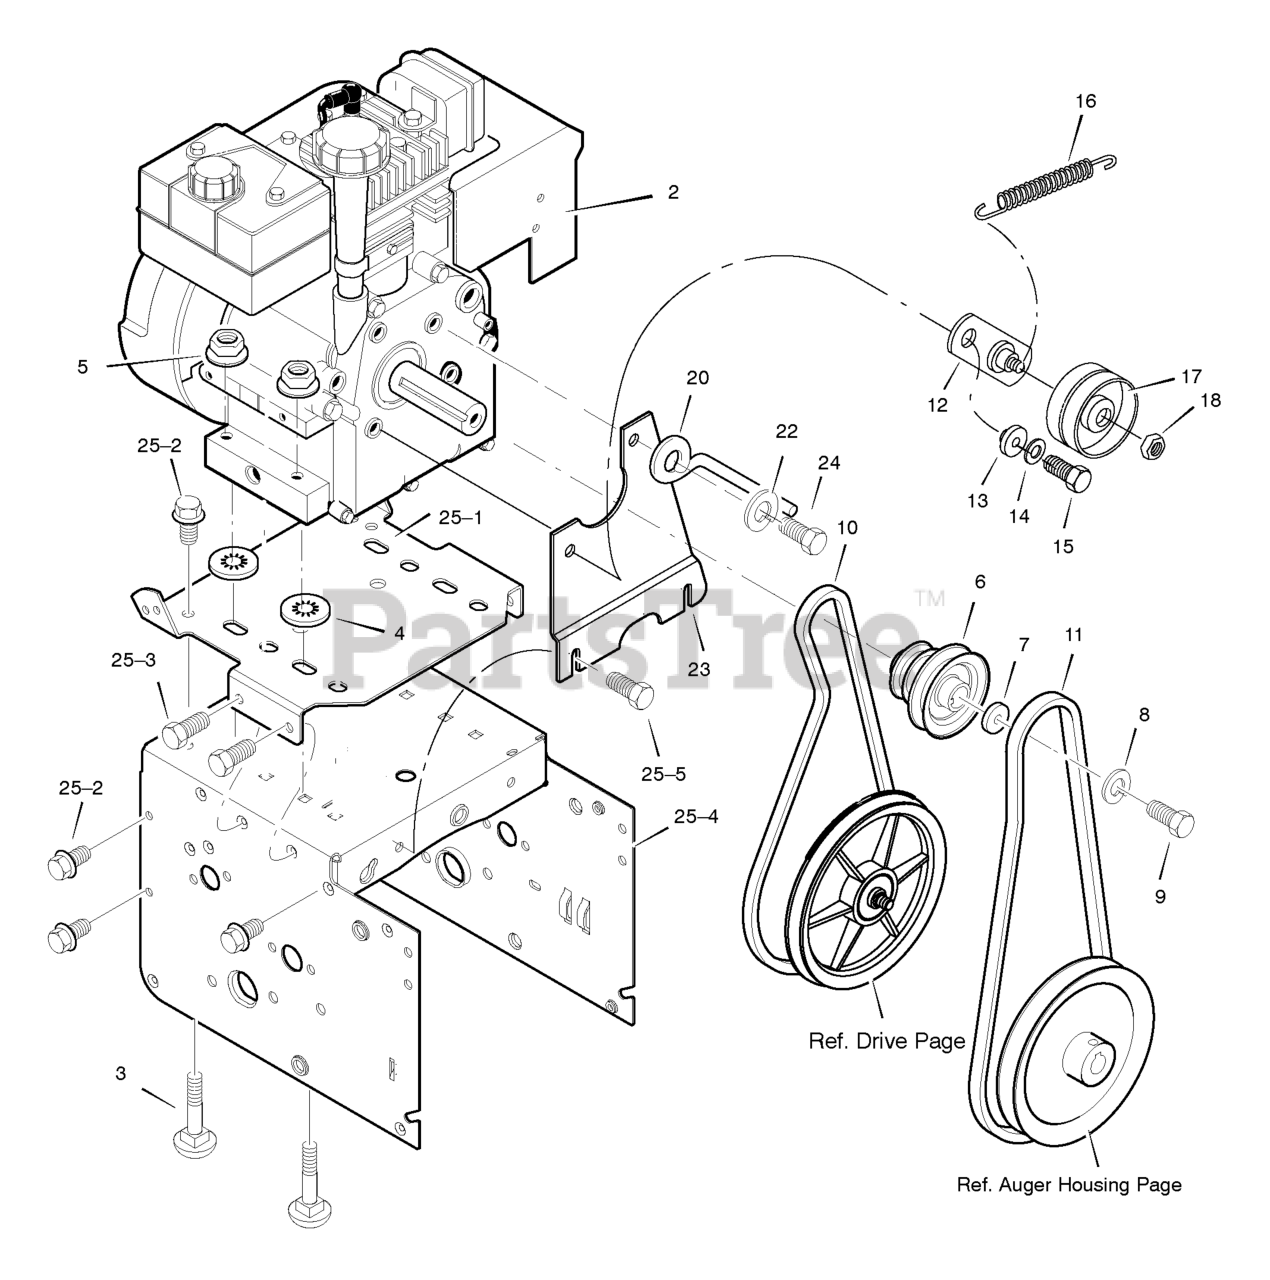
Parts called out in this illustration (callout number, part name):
2	ENGINE
3	BOLT, CARRIAGE 5/16-18
4	RETAINER, PUSH
5	NUT, HEX 5/16-18
6	PULLEY, ENGINE
7	WASHER
8	WASHER .38ID
9	SCREW, 3/8-24 x 1.00
10	BELT, DRIVE V 3L
11	BELT, AUGER V 4L
12	BRACKET ASSEMBLY, IDLER
13	BUSHING, IDLER BRACKET
14	WASHER, SPLIT
15	SCREW 5/16-24 X 1.00
16	SPRING, IDLER TRACTION DRIVE
17	PULLEY, IDLER
18	NUT, JAM 3/8-16
20	GUIDE, BELT
22	WASHER, SPTLK .31X.58X.08
23	PLATE, ANTI VIBRATION
24	SCREW, 5/16-24 x 1.00
25	FRAME ASSEMBLY
25-1	PLATE, ENGINE MOUNT
25-2	SCREW, TAP 1/4-20 X .63
25-3	SCREW, TAP 5/16-18 X .50
25-4	FRAME, MOTOR BOX
